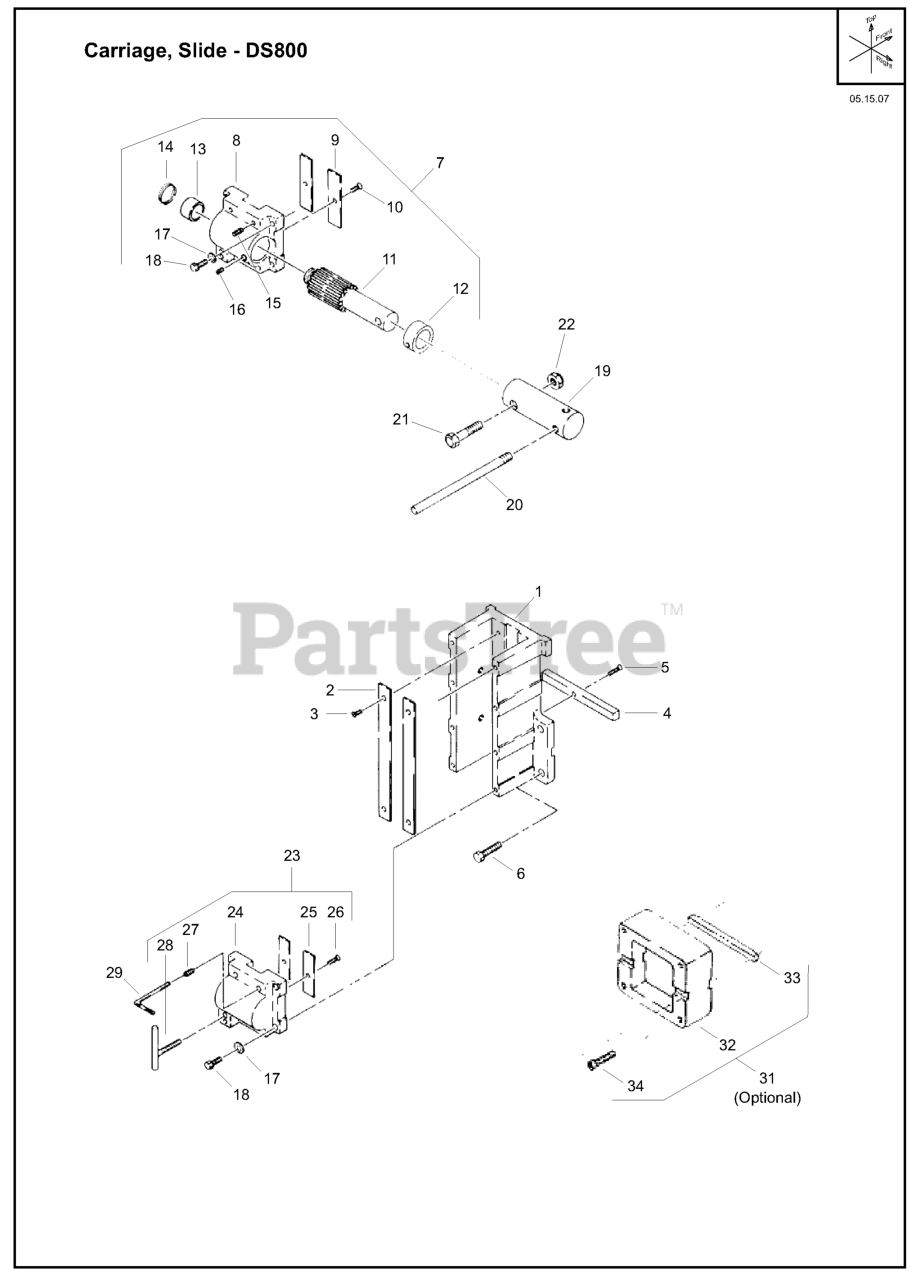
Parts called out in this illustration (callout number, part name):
1	Body, Carriage, Husq Orange
2	Plate, Wear, .75 x 9.50"
3	Screw, FL Hd Mach, #8-32 x .375 Brass
4	Key, .375 Sq x 3.63"
5	Screw, FL Hd Mach, #8-32 x .75 Brass
6	HCS 3/8C X 1 1/2
7	Pinion Bracket - compl
8	Bracket, Pinion, Husq Orange
9	Plate, Wear, .62 x 2.88"
10	Screw, FL Hd Mach, #8-32 x .375 Brass
11	Gear, Pinion, DS800
12	Bushing, 1.129ID x 1.378OD x .750
13	Bushing, .753ID x 1.003OD x .750
14	Retaining Ring .750 D
15	Screw, Soc Hd, .25-20 x .75 HK
16	Screw, Soc Hd, .25-20 x .312 Dog Pt
17	Lockwasher, .3125 Int. Tooth
18	Capscrew, Hex Hd, .3125-18 x 1.25
19	Hub, Handle, Carriage DS800
20	Handle, Carriage DS800
21	Capscrew, Hex Hd, 1/2-13 x 2-1/4
22	Locknut, Fiber .5-13
23	Lower Bracket - compl
24	Bracket, Brake, Husq Orange
25	Plate, Wear, .62 x 2.88"
26	Screw, FL Hd Mach, #8-32 x .375 Brass
27	Screw, Soc Hd Set, .25-20 x .75 HK
28	Screw, Lock - Lower Bracket
29	Wrench, Key, 1/8" Allen Type
31	Kit, 2" Spacer Block, DS800
32	Block, 2" Spacer, Husq Orange
33	Key, .50 Sq x 5.88"
34	Capscrew, Hex Hd, .375-16 x 3.5
